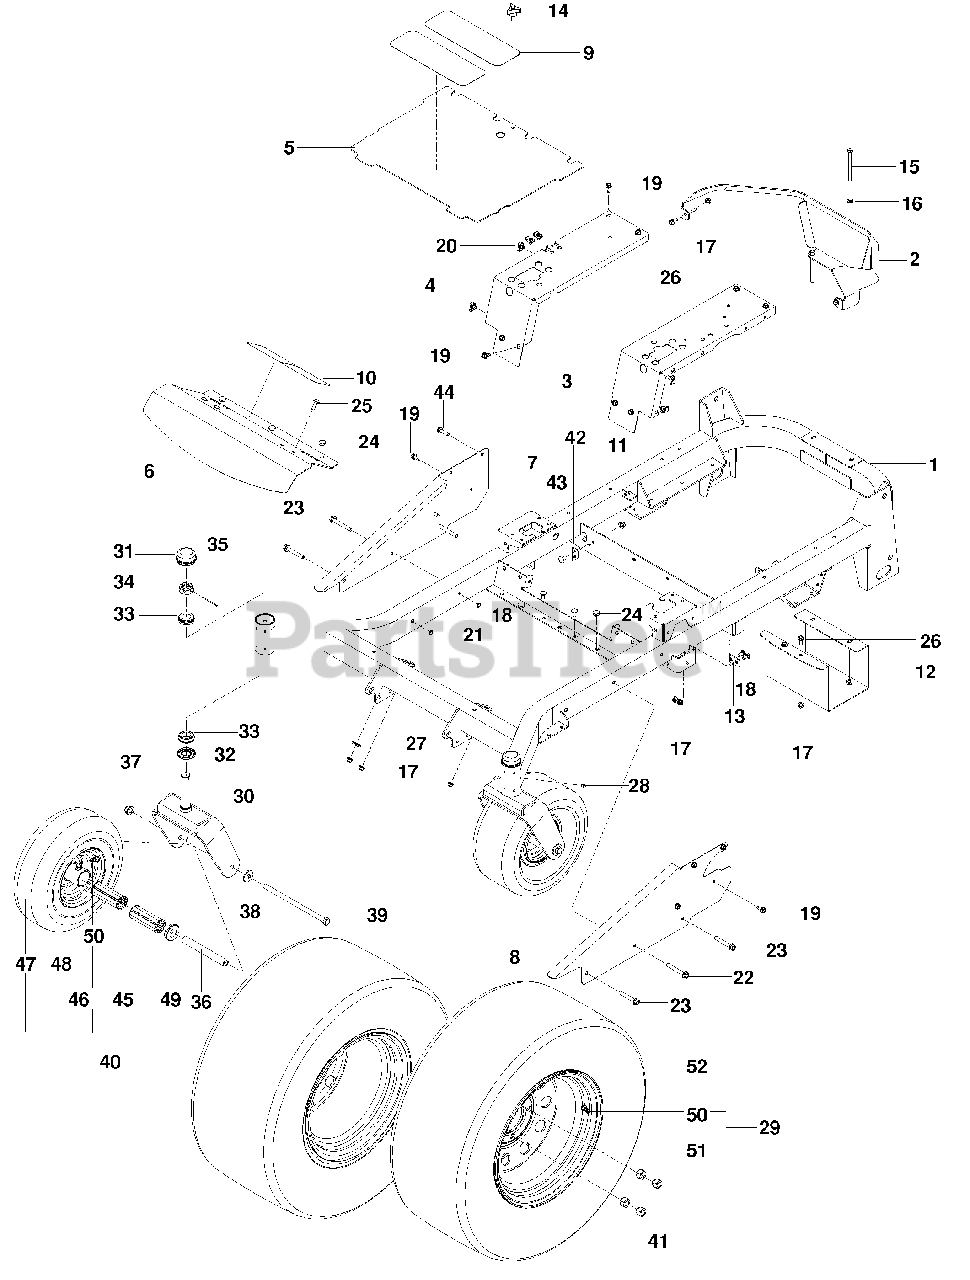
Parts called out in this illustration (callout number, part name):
1	FRAME w/ SAFETY DECALS
2	GUARD, REAR
5	PLATE, FLOOR w/ DECALS
6	PLATE, FOOTREST
9	PAD, ABRASIVE LG
10	PAD, ABRASIVE SM
11	NUT 3/8-16 HEX FLG NYLOC
12	SHIELD, MUFFLER
13	STOP, DECK
14	KNOB w/ STUD
15	HCS 5/16-18 x 4
16	WASHER 5/16 SAE FLAT
17	NUT 5/16-18 FLANGE NYLOC
18	BOLT, RD HD 5/16-18 x 3/4
19	BOLT 5/16-18 x 3/4 THD FRM
20	RETAINER, U TYPE 5/16-18
21	NUT 3/8-16 HEX JAM NYLOC
22	SCREW, HX FLG 3/8-16 x 2 3/4
23	SCREW, HX FLG 3/8-16 x 2 1/2
24	GROMMET, BUMPER
25	BOLT, RD HD 5/16-18 x 1
26	HHFS 5/16-18 x 3/4
29	WHEEL ASSY, REAR
30	YOKE, CASTER
31	GREASE CAP
34	SLOTTED JAM NUT 1"-14
35	COTTER PIN 1/8 x 2
36	SPACER, PIVOT
37	NUT 1/2-13 HEX FLG NYLOC
38	WASHER 1/2 FLAT ZD
39	HCS 1/2-13 x 9 1/2
40	TIRE ASSM
42	BRACKET, DAMPENER
43	BOLT, RD HD 3/8-16 x 3/4
44	HHFS 5/16-18 x 1 1/4 TPBLT
45	CAGE BEARING 3 1/4
46	ZERK
47	TIRE, CASTER
48	RIM, CASTER TIRE
49	BEARING, FLANGE
